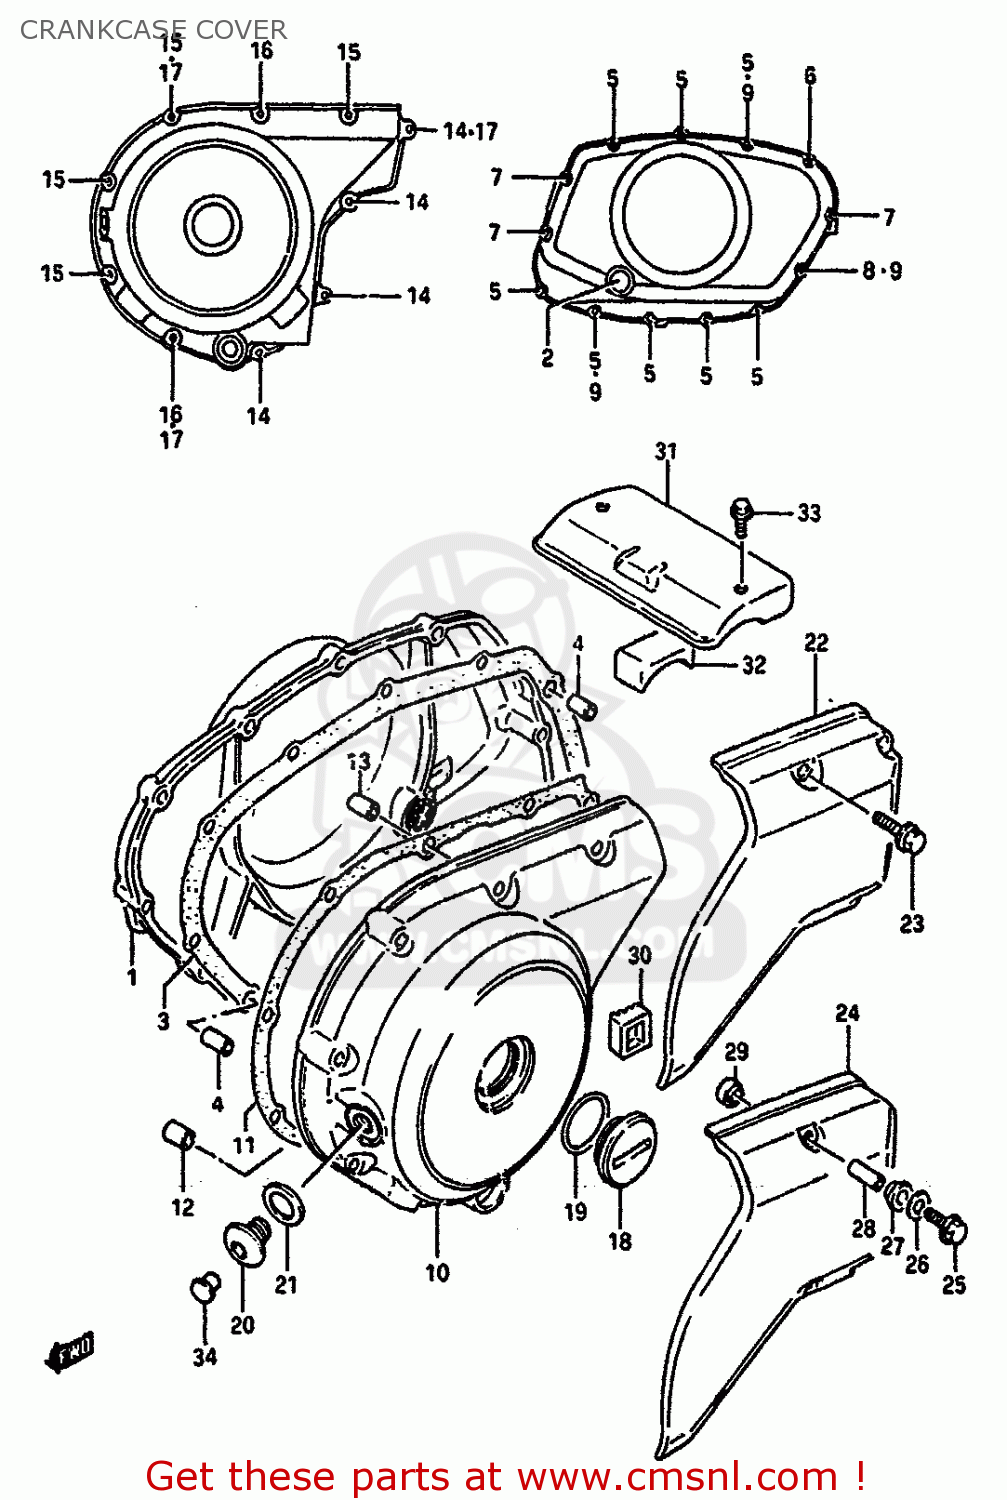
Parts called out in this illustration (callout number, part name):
1	COVER,CLUTCH
2	LENS,OIL LEVEL CHECK
3	GASKET,CLUTCH COVER (NAS)
4	PIN
5	BOLT
6	BOLT
7	BOLT
8	BOLT
9	GASKET(5.8X13X1.2) (NAS)
10	COVER
11	GASKET,MAGNETO COVER (NAS)
12	PIN (11X20)(SUS)
13	PIN
14	BOLT
15	BOLT
16	BOLT
17	GASKET(5.8X13X1.2) (NAS)
18	Chrome Crankshaft Plug
19	O RING(D:3.1,ID:32.7)
20	PLUG,14X12
21	GASKET(14X19.2X2) (NAS)
22	COVER,SECONDARY DRIVE
23	BOLT
24	COVER,SECONDARY GEAR CASE
25	BOLT
26	WASHER
27	WASHER(8.7X15X2.1)
28	SPACER
29	WASHER(8.7X16X5)
30	DAMPER,SECONDARY COVER
31	COVER,STARTER MOTOR
32	DAMPER,MOTOR COVER
33	BOLT
34	CAP(OD:12)
